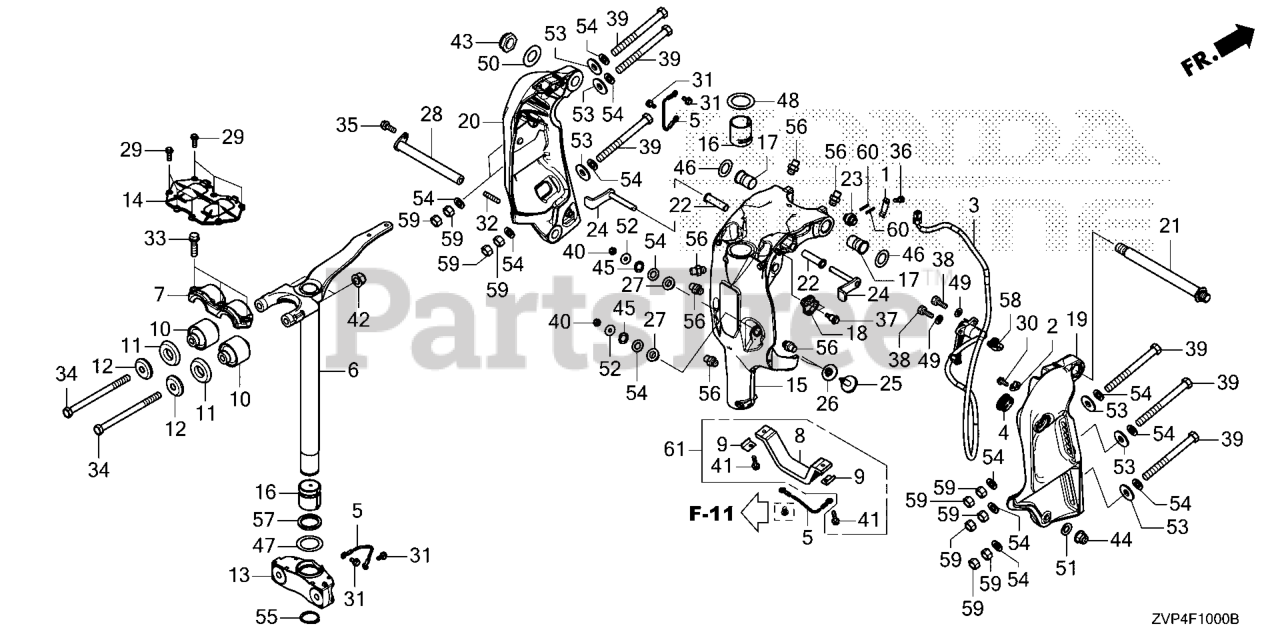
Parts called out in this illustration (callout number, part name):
1	SPRING, CLICK
2	BRACKET, HARN CLIP D
3	SENSOR ASSY.
4	GROMMET, SENSOR HARN
5	WIRE, LEAD (1.5X116MM)
6	FRAME, MOUNT *NH565*
6	FRAME *NHB14M*
7	HSG, MNT (UPPER)
8	METAL, ANODE
9	PLATE, ANODE METAL
10	MOUNT COMP, RUBBER
11	RUBBER, MNT STOPPER
12	STOPPER, MOUNT
13	HSG, MT CTR (LOWER)
14	COVER, MOUNT (UPPER)
15	CASE, SWIVEL *NH565*
15	CASE *NHB14M*
16	LINER, SWIVEL CASE
17	BUSH, SWIVEL CASE
18	CAM, TRIM/TILT ANGLE
19	BRACKET *NH565*
19	BRACKET *NHB14M*
20	BRACKET *NH565*
20	BRACKET *NHB14M*
21	SHAFT, TILTING
22	BUSH, TILT ARM
23	BRACKET, TILTING
24	STOPPER, TILT
25	RECEIVER, THRUST
26	BUSH A, THRUST RECEIVE
27	BUSH B, THRUST RECEIVE
28	SHAFT, CYLINDER (LOWER)
29	BOLT, FLANGE (6X20) (ENGINE NO.)
30	BOLT-WASHER (6X16)
31	BOLT, FLANGE (6X12) Use from Frame SN 1005249.
32	BOLT, STUD (10X28)
33	BOLT-WASHER (10X37)
34	BOLT, HEX. (14X205)
35	BOLT, FLANGE (8X22)
36	BOLT, HEX. (6X14)
37	BOLT, SPECIAL (6X22)
38	BOLT, HEX. (6X20)
39	BOLT, HEX. (12X150)
39	BOLT, HEX. (12X180)
39	BOLT, HEX. (12X130)
40	NUT, SELF-LOCK (6MM)
41	BOLT, FLANGE (6X25) (SUS-D)
42	NUT (14MM)
43	NUT, SELF-LOCK (7/8-14UNF)
44	NUT, FLANGE (10MM)
45	WASHER, WAVE (12MM)
46	WASHER, WAVE (26MM)
47	WASHER, WAVE (45MM)
48	WASHER (45MM)
49	WASHER, PLAIN (6MM) Use up to Frame SN 4800342.
50	WASHER (7/8")
51	WASHER, PLAIN (10MM)
52	WASHER, PLAIN (6MM)
53	WASHER, PLAIN (12MM)
54	WASHER, PLAIN (12MM)
55	CIRCLIP, EX (44)
56	NIPPLE, GREASE
58	CLIP, HARNESS BAND (175.2MM) (DARK GRAY)
59	NUT, HEX. (12MM)
60	PIN, SPRING (3X20)
61	METAL KIT, ANODE
